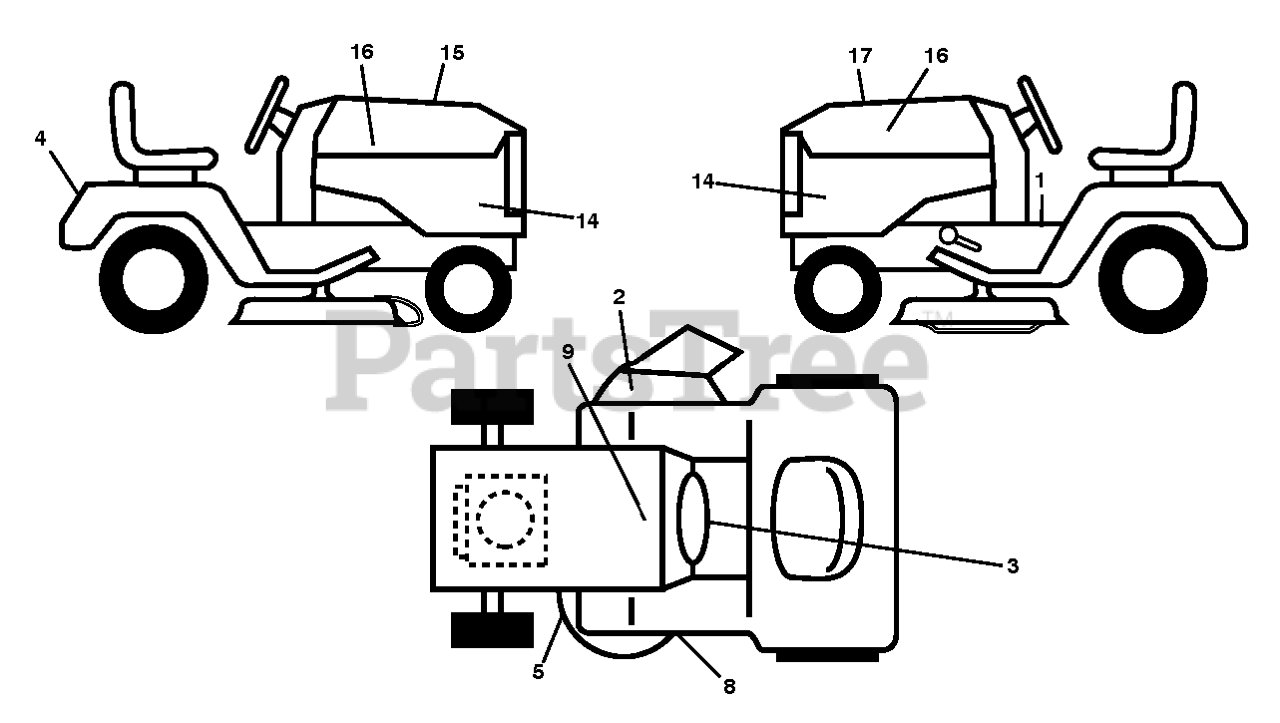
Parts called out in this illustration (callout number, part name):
1	DECAL.WARN.START.INSTRUCTIONS
2	DECAL.WARN.KEEP.HAND.AWAY
3	DECAL, WARNING SPARK ARRESTOR
4	DECAL.FENDER
5	DECAL.MOWER
8	DECAL.MOWER.SCH.48/54
9	DECAL BTRY SYMBOLS
14	DECAL.SIDE.PANEL.YTH24K48
15	DECAL.WARNING.CUST.RESP.E85.
16	DECAL.BADGE.170MM.TEXTLOGO.
